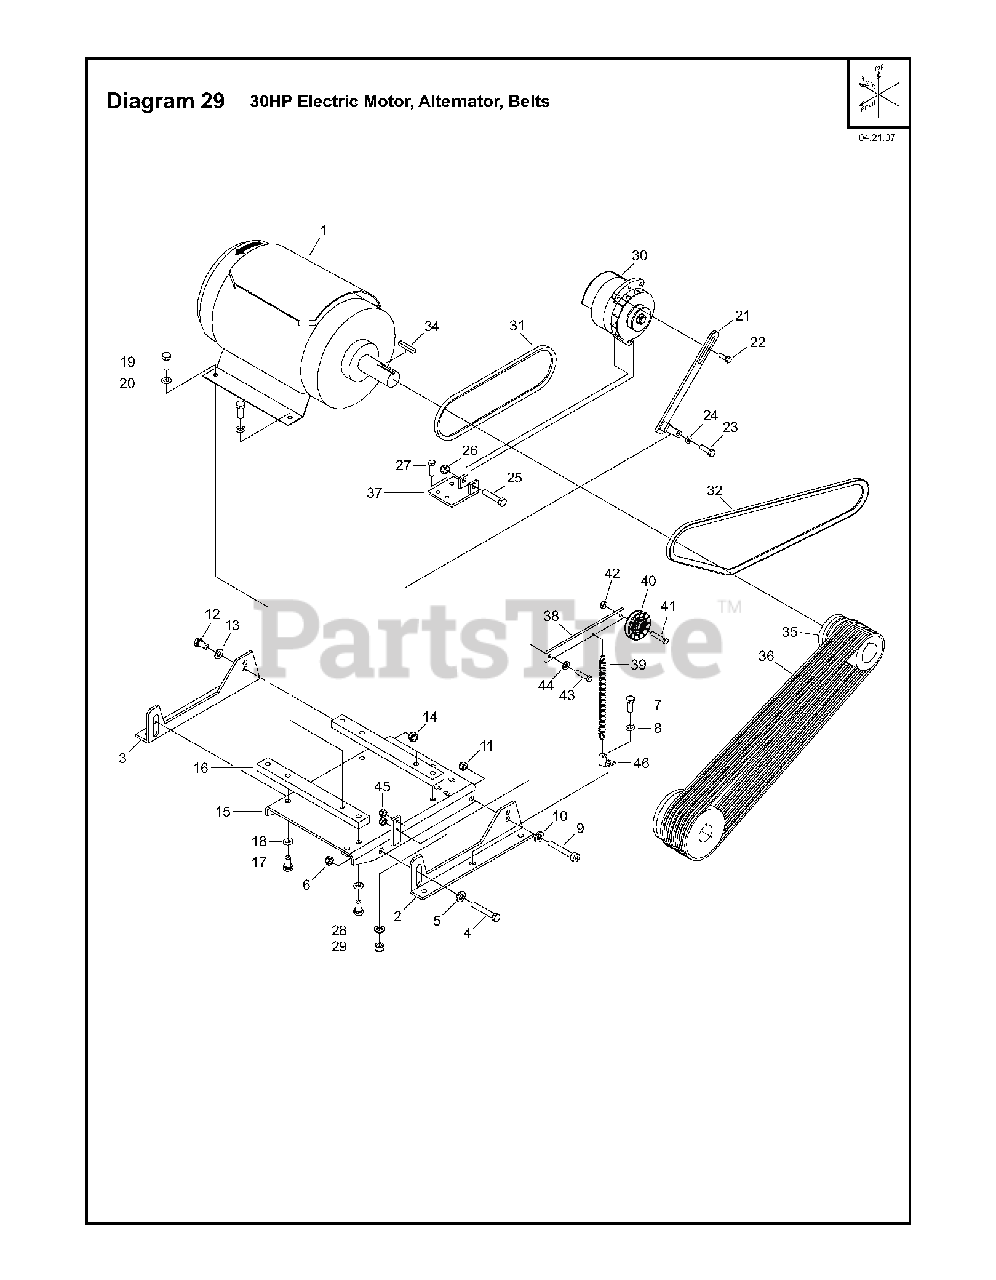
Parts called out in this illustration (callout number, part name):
2	BRACKET. ENGINE BASE LH PTD
3	BRACKET. ENGINE BASE RH. BLACK
5	WASHER
6	LOCKNUT. FIBER M12 DIN 985 Z/P
7	HHCS. M12 x 1.75 x 30 DIN933ZP
8	LOCKWASHER. SPLIT .5 Z/P
9	SHCS. M12 x 1.75 x 40mm
10	WASHER
11	LOCKNUT. FIBER M12 DIN 985 Z/P
12	HHCS. M12 x 1.75 x 30 DIN933ZP
13	WASHER
14	LOCKNUT. FIBER M12 DIN 985 Z/P
15	BASE. MOTOR-20HP EL METRIC BLK
16	SCREW
17	HHCS. M12 x 1.75 x 25 DIN933ZP
18	LOCKWASHER. SPLIT .5 Z/P
20	LOCKWASHER. SPLIT .5 Z/P
21	ALTERNATOR BRKT WLDMNT. BLACK
22	FLNGBLT. 5/16-18 X 1 GR5 Z/P
23	HHCS. M10 x 1.5 x 25 DIN933 ZP
24	LOCKWASHER. SPLIT M10
25	HHCS. M12 x 1.75 x 65 DIN931ZP
26	LOCKNUT. FIBER M12 DIN 985 Z/P
27	HHCS. M10 x 1.5 x 40 DIN933 ZP
29	LOCKNUT. FIBER M10 DIN 985
30	ALTERNATOR. 12V 37AMP #YB69
32	V-BELT
34	KEY. SQ .5 X 2.5" LG.
35	INSERT.LENS.RFLCT.HUSQ
35	SKIRT.REAR.21".HI-VAC.BLACK
36	V-BELT
37	BRACKET. MTG - ALT BLK
38	IDLER LEVER - PC BLACK
42	LOCKNUT. FIBER M10 DIN 985
45	LOCKNUT. FIBER M10 DIN 985
46	DECAL
